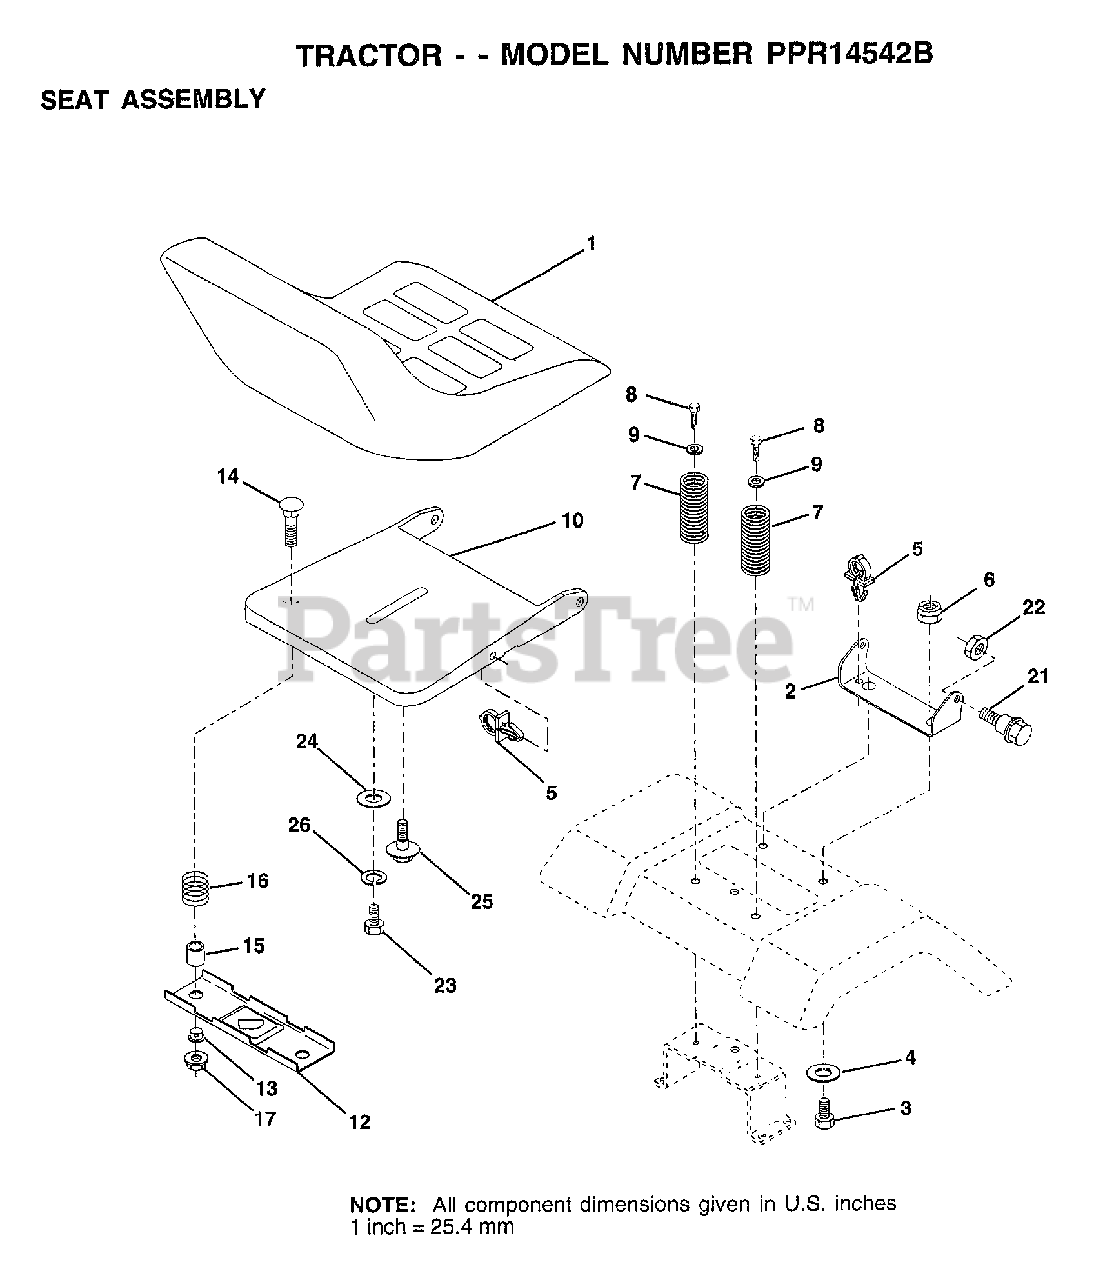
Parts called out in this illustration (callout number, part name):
1	SEAT
2	BRACKET PVT SEAT
3	BOLT
4	WASHER PM
5	CLIP.PUSH-IN.HING
6	NUT
7	SPRING COMPRESSIO
8	SCREW
9	WASHER
10	PAN-SEAT
12	BRKT SWITCH
13	BUSHING
14	BOLT-RD HD SQ NK
15	SPLIT SPACER
16	SPRING
21	"BOLT,SHOULDER"
22	NUT
23	BOLT
24	WASHER
25	"BOLT,SHOULDER"
26	LOCKWASHER
